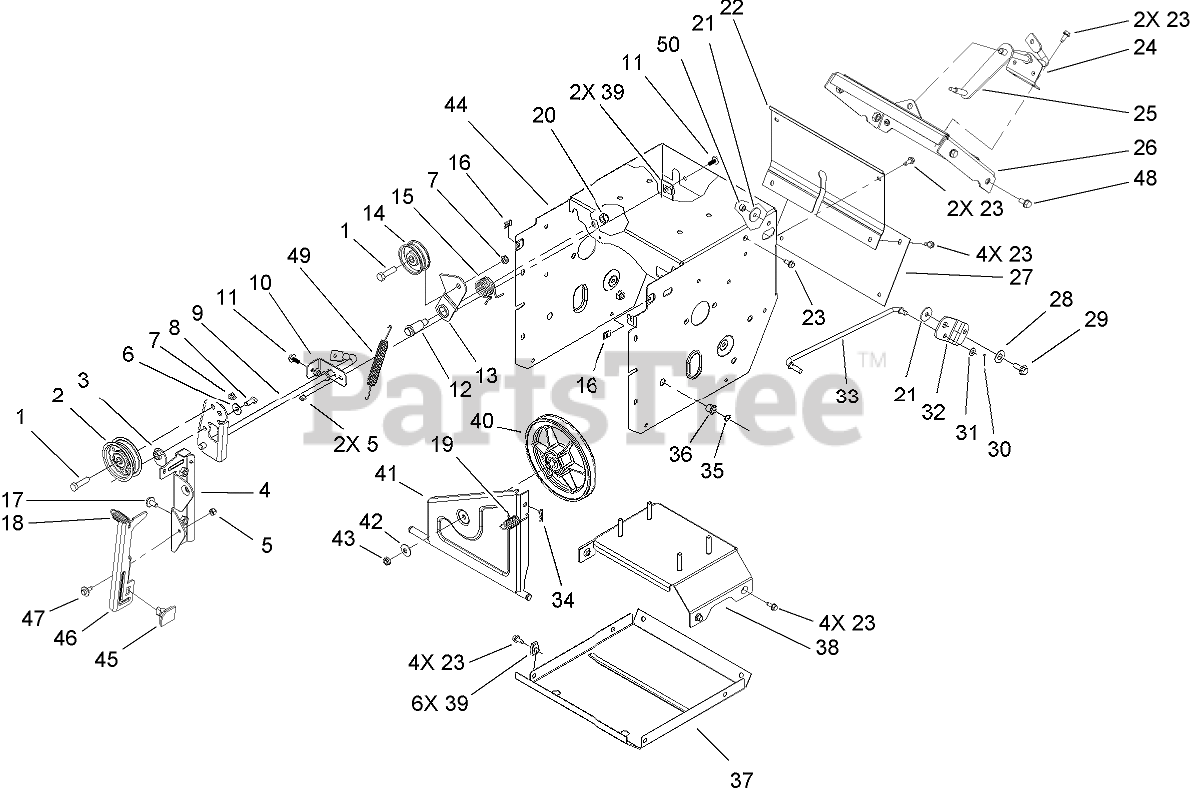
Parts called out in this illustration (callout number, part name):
1	SCREW-HH
2	PULLEY-IDLER
4	BRACKET-IDLER, IMPELLER
5	NUT-LOCK, NI
6	WASHER-BELLEVILLE
7	NUT-LOCK, NI
8	SCREW-HH
9	IMPELLER CLUTCH ASM
10	BRACKET-REAR, CLUTCH
11	SCREW-HHF
12	BOLT-SHOULDER
13	ARM-IDLER, TRACTION
14	PULLEY-IDLER
15	SPRING-TORSION
16	NUT-SPEED, U-TYPE
17	SCREW-HHF
18	SPRING-EXTENSION
19	SPRING-EXTENSION
20	NUT-LOCK, NI
21	WASHER-PIVOT
22	COVER-UPPER
23	SCREW-HWH
24	BRACKET-ROD, SHIFT
25	LEVER-CONTROL, TRACTION
26	SHIFT PLATE ASM
27	COVER-LOWER
28	WASHER
29	SCREW-SHOULDER
30	PIN-COTTER
31	WASHER-PLAIN
32	BELLCRANK-DRIVE
33	LINK-CONTROL, SPEED
34	PIN-COTTER
35	RING-RETAINING
36	BUSHING-NYLINER
37	PAN-BOTTOM
38	BRACE FRAME ASM
40	PULLEY-TRACTION
41	BRACKET-WHEEL, FRICTION
42	WASHER-BELLEVILLE
43	NUT-HEX
44	TRACTION FRAME ASM
45	PAD-BRAKE
46	ARM-BRAKE
47	SCREW-SHOULDER
48	SCREW-HWHTF
49	SPRING-EXTENSION
50	NUT-LOCK, NI
